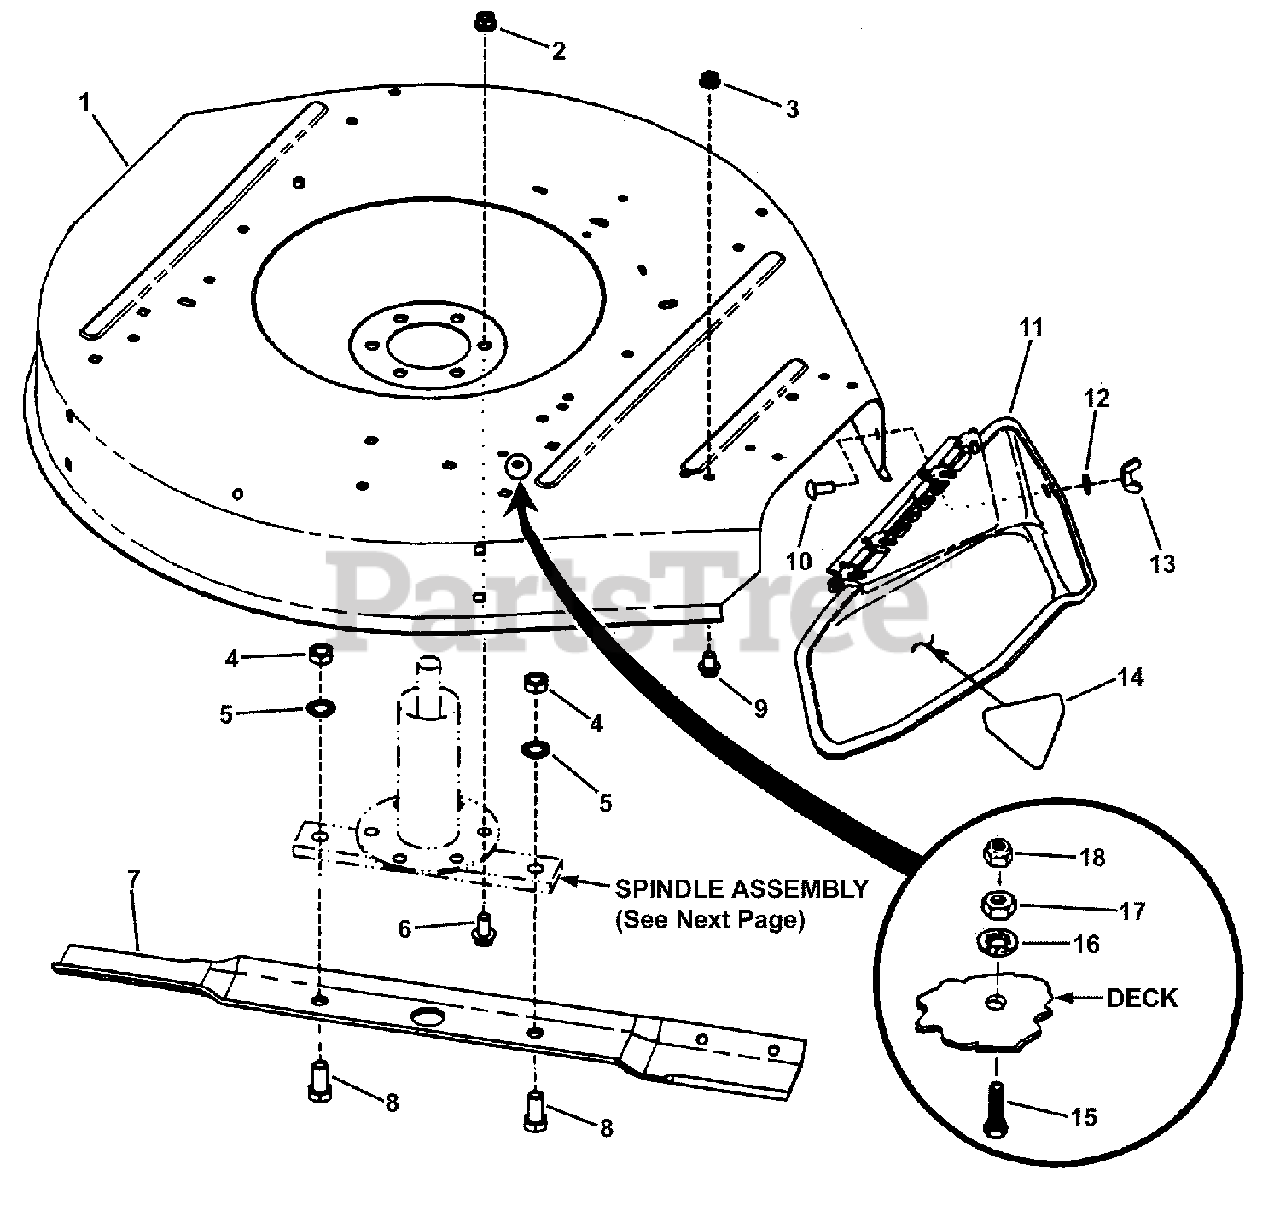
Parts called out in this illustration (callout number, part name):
1	DECK, 26"
2	NUT, 3/8-16 Hex Flange Lock
3	NUT, 5/16-18 Hex Flange Lock, GR5
4	NUT, 1/2-20 Hex-Jam
5	WASHER, 1/2" Internal Tooth Lock
6	BOLT, 3/8-16 x 3/4" Hex Flange Lock
7	BLADE, 26"
8	SCREW, 1/2-20 x 1" Hex Cap
9	BOLT, 5/16-18 x 1/2" Hex Flange Lock GR5
10	BOLT, 5/16-18 x 3/4" Short Neck Carriage, GR5
11	DEFLECTOR, 26" Discharge
12	WASHER, 5/16" Flat
13	WING-NUT, 5/16-18
14	DECAL, Danger, Cut Finger
15	SCREW, 1/4-20 x 1" Hex Head Cap GR5
16	WASHER, 1/4" Internal Tooth Lock
17	NUT, 1/4-20 Hex
18	NUT, 1/4-20 Hex Nyloc
